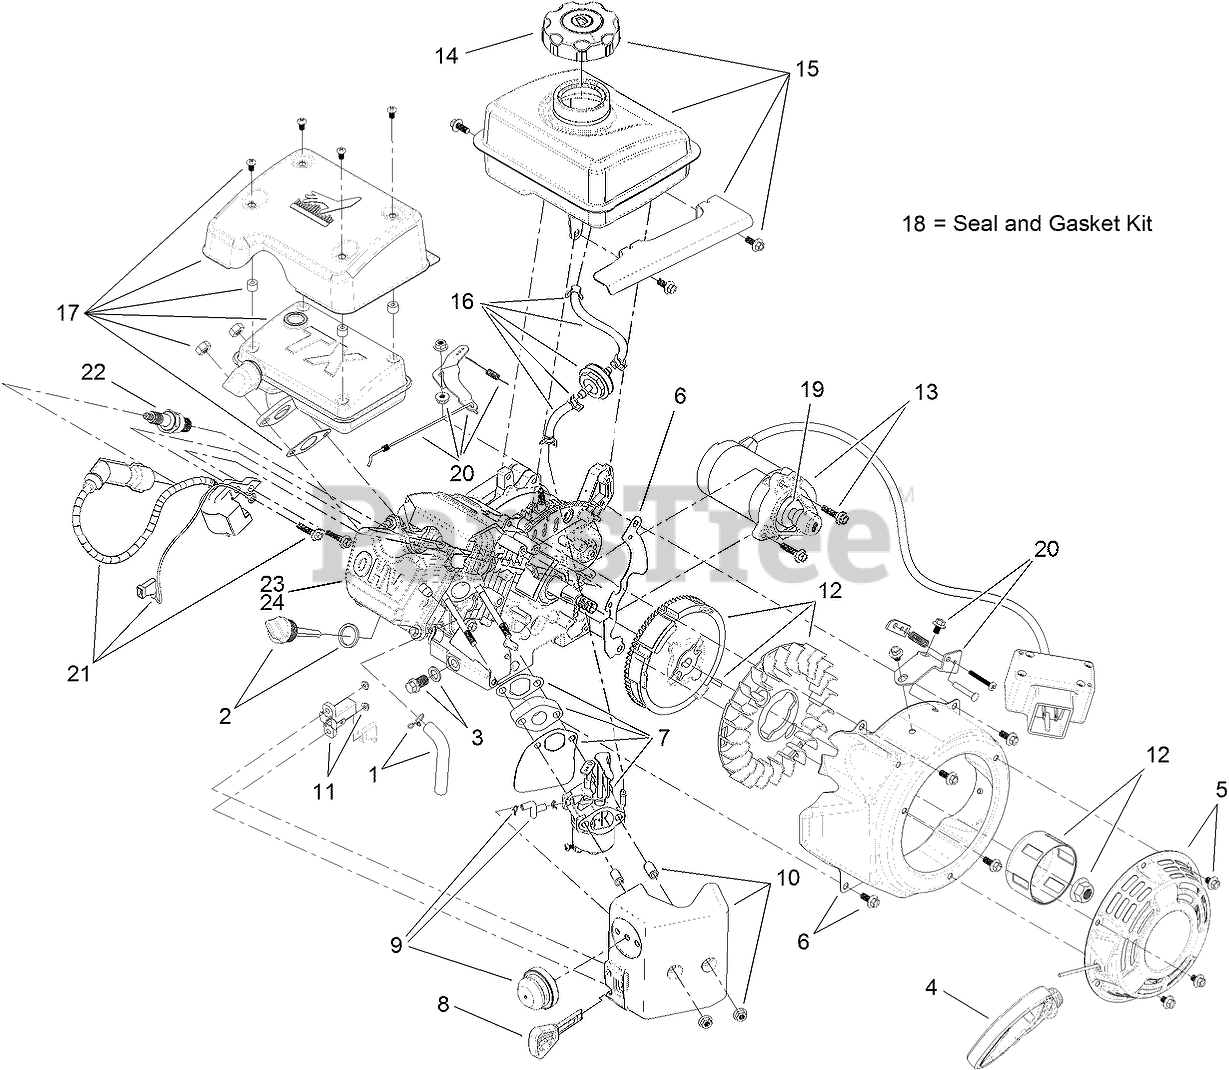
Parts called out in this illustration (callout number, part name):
1	BREATHER TUBE KIT
2	DIPSTICK AND O-RING KIT
3	DRAIN PLUG KIT
4	MITTEN GRIP KIT
5	RECOIL ASM KIT
6	BLOWER SHROUD KIT
7	COMPLETE CARB SERVICE KIT
8	KEY AND LANYARD KIT
9	PRIMER BULB KIT
10	HEATER BOX KIT
11	SWITCH KIT
12	FLYWHEEL KIT
13	ELECTRIC STARTER KIT
14	FUEL CAP ASM
15	FUEL TANK AND CAP ASM
16	FILTER, FUEL LINE AND CLAMP KIT
17	MUFFLER KIT
19	PINION KIT
20	GOVERNOR ARM, SPRING, LINK, HARDWARE KIT
21	IGNITION KIT
22	SPARK PLUG
23	GASKET-COVER, VALVE
24	VALVE COVER ASM
